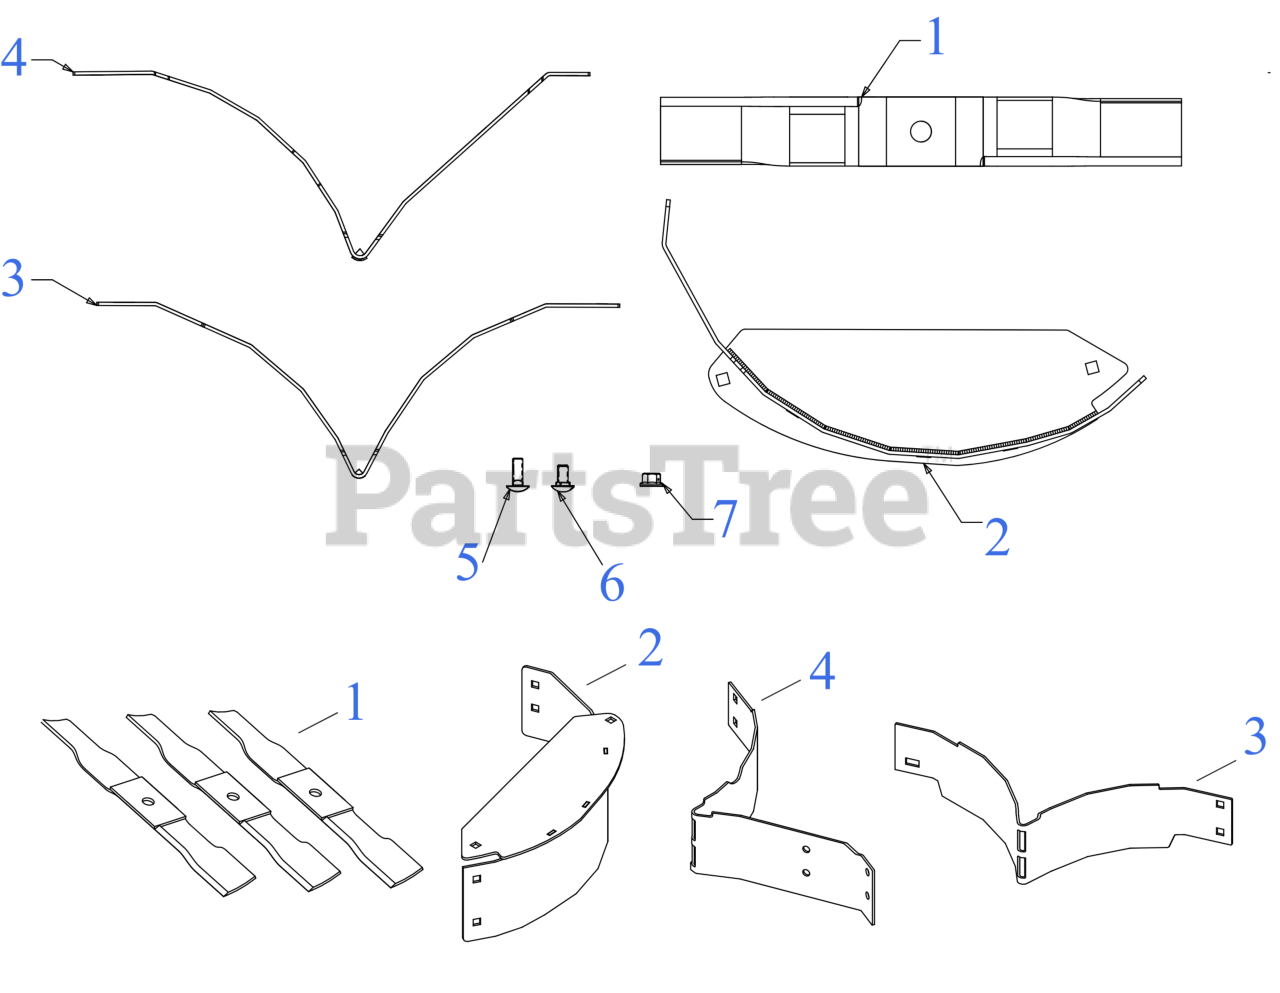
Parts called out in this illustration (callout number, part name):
1	BLADE-19"MULCH 54"
2	54" DISCHARGE MULCH BAFFLE
5	CARRIAGE BOLT 3/8-16 x 1.00 GR5
6	CARRIAGE BOLT 3/8-16 x .75
7	NUT-CTRLCK FLG HEX
